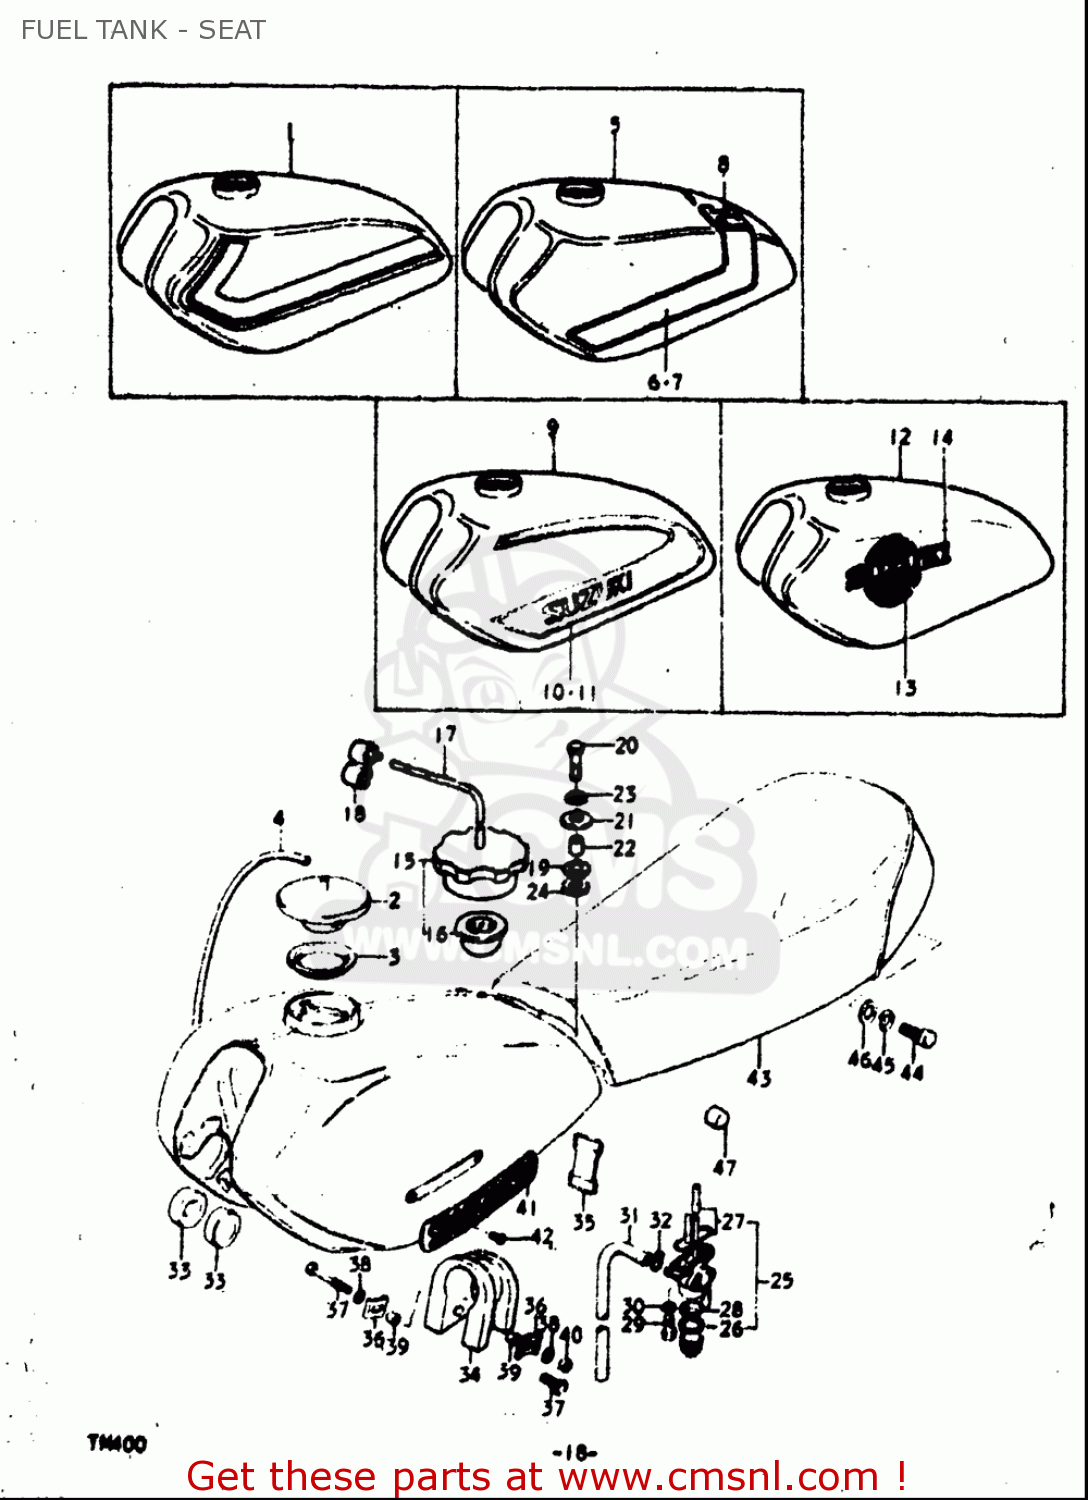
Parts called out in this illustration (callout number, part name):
4	HOSE(5X8.2X2000)
15	CAP ASSY,FUEL TANK FILLER
17	HOSE(5X8.2X600)
18	CLAMP,FUEL TANK BREATHER HOSE
19	CUSHION
20	BOLT
21	WASHER (8.5X30X2.3)
22	SPACER(8.2X12X17)
23	WASHER,LOCK
25	COCK ASSY,FUEL
26	GASKET,FILTER (NAS)
27	FILTER SET,FUEL COCK
28	NET,STRAINER
29	SCREW
30	GASKET(5.8X13X1.2) (NAS)
31	HOSE(5X9X600)
32	CLIP
33	CUSHION
35	BAND
37	BOLT
38	WASHER
39	SPACER(6.1X8X5.2)
40	NUT
42	SCREW
44	BOLT
45	WASHER,LOCK
46	WASHER
47	CUSHION(11.5X22X20)
